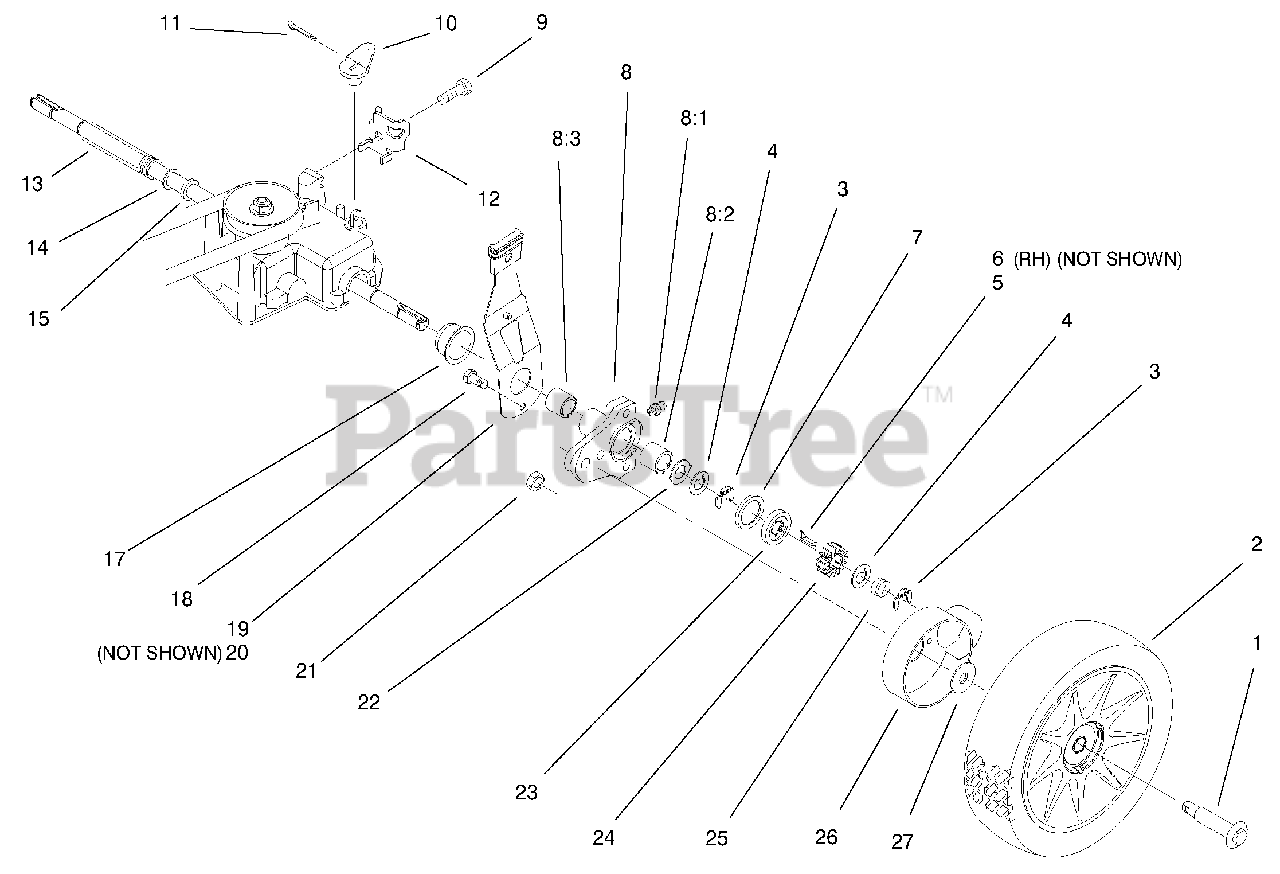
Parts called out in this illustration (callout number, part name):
1	Bolt-Shoulder
2	Wheel ASM w/Gear
3	Ring-Klip, Sp
4	Washer-Thrust, Keyed
5	Key-Rocking, LH
6	Key-Rocking, RH
7	Ring-Friction
8	Rear Height Adj. Arm ASM
8:1	Fitting-Zerk
10	Lever-Shift
11	Pin-Cotter
12	Clamp-Cable
13	Cover-Shaft, Drive
17	Ring-Isolator
19	LH Rear Spring Arm ASM
20	RH Rear Spring Arm ASM
22	Washer-Arm, Pivot
24	Pinion-Gear, 15t
25	Spring-Compression
26	Cover-Wheel
27	Washer-Stepped
